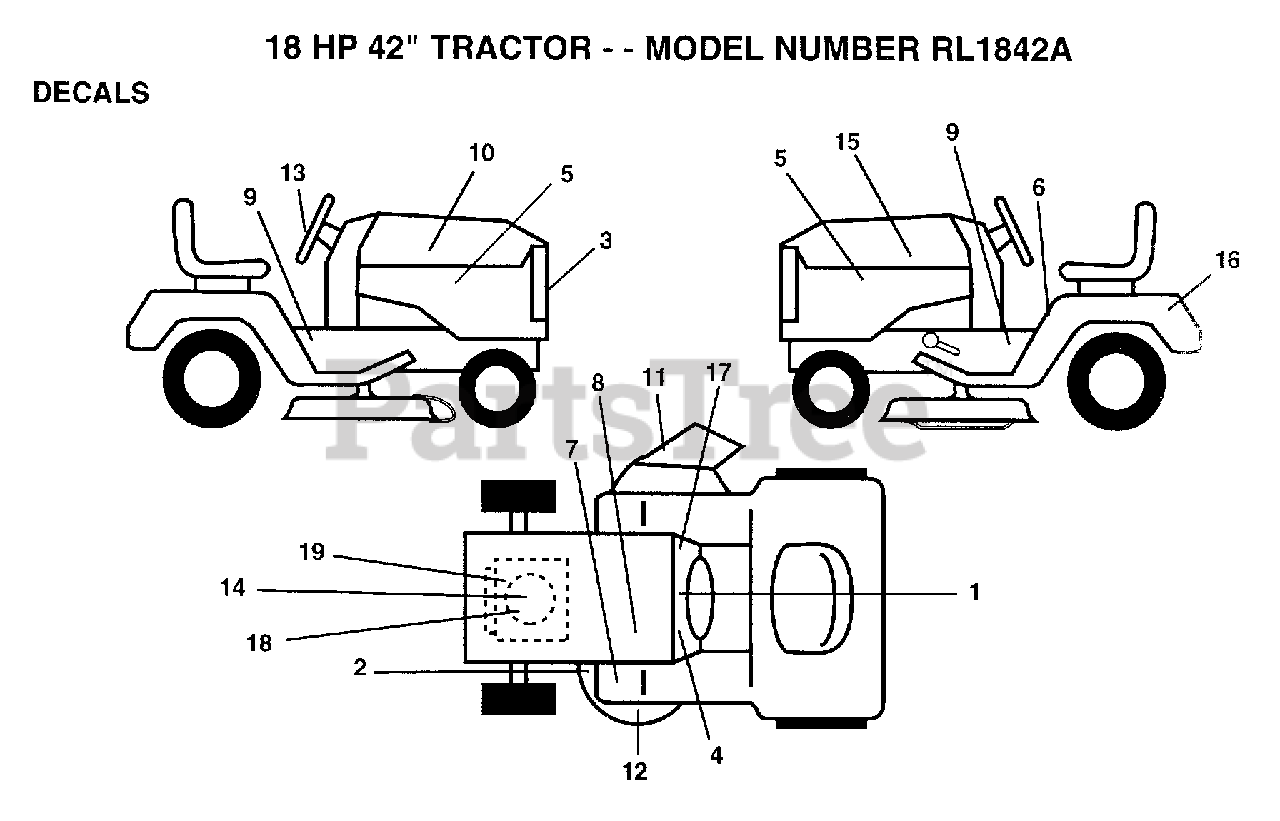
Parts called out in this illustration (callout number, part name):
2	DECAL
3	GRILL DECAL
5	DECAL.HOOD.INSERT
6	DECAL CAUTION
7	DECAL T
8	DECAL
9	CHASSIS DECAL
11	"DECAL, WARNING"
13	"DECAL,STR WHL"
14	DECAL.ENG.272757
16	FENDER DECAL
18	DECAL.ENG.272101
